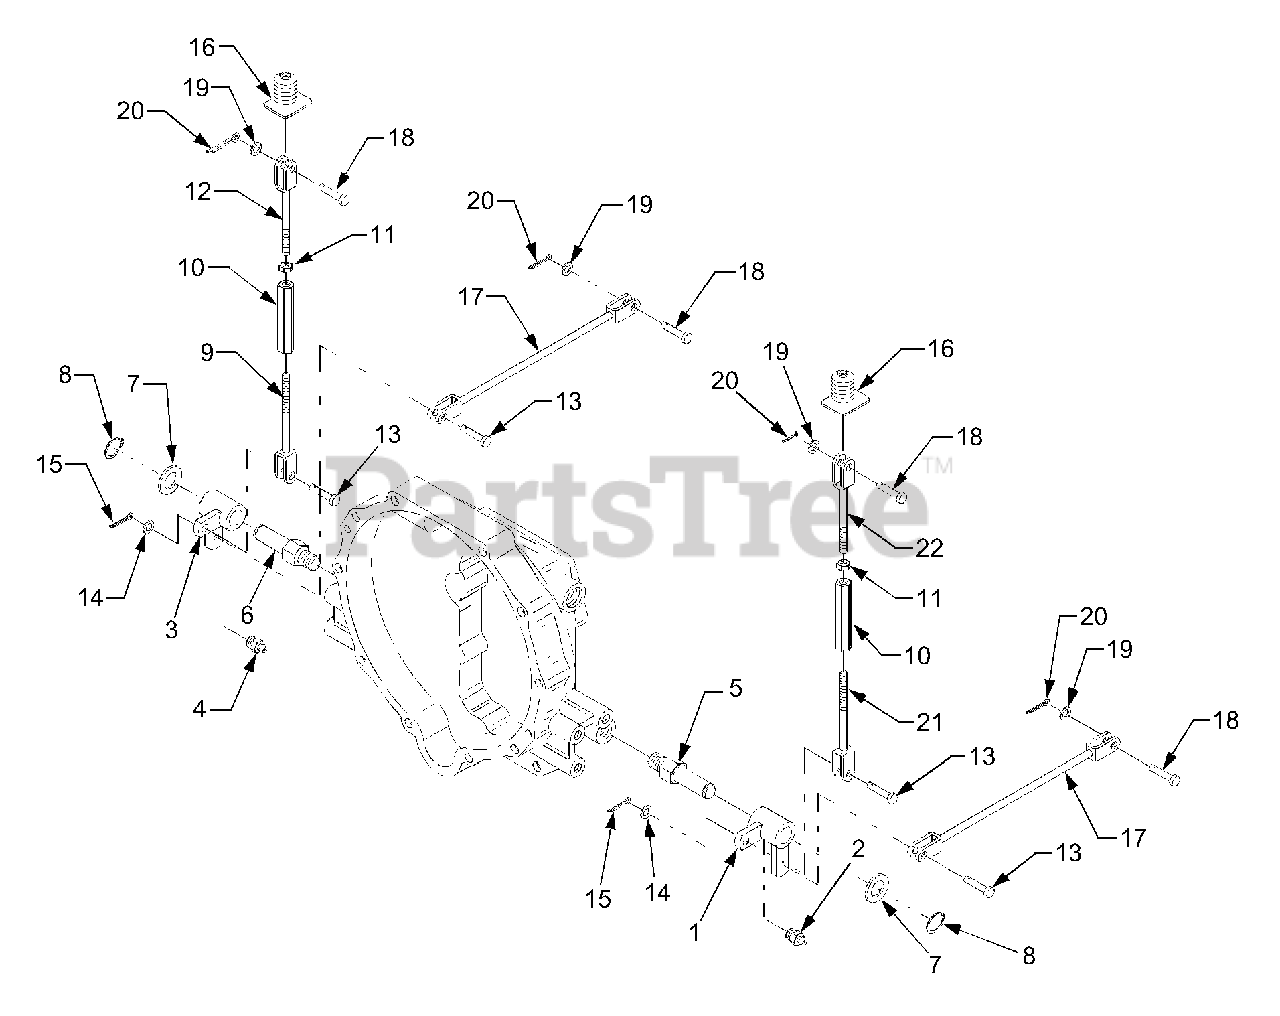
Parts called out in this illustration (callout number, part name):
1	Lever, Brake(LH)
2	Nipple, Grease
3	Lever, Brake(RH)
4	Nipple, Grease
5	Shaft, Brake(LH)
6	Shaft, Brake(RH)
7	Washer, Plain
14	Washer, Plain
19	Washer, Plain
21	Rod 1, Brake(LH)
22	Rod 2, Brake(LH)
